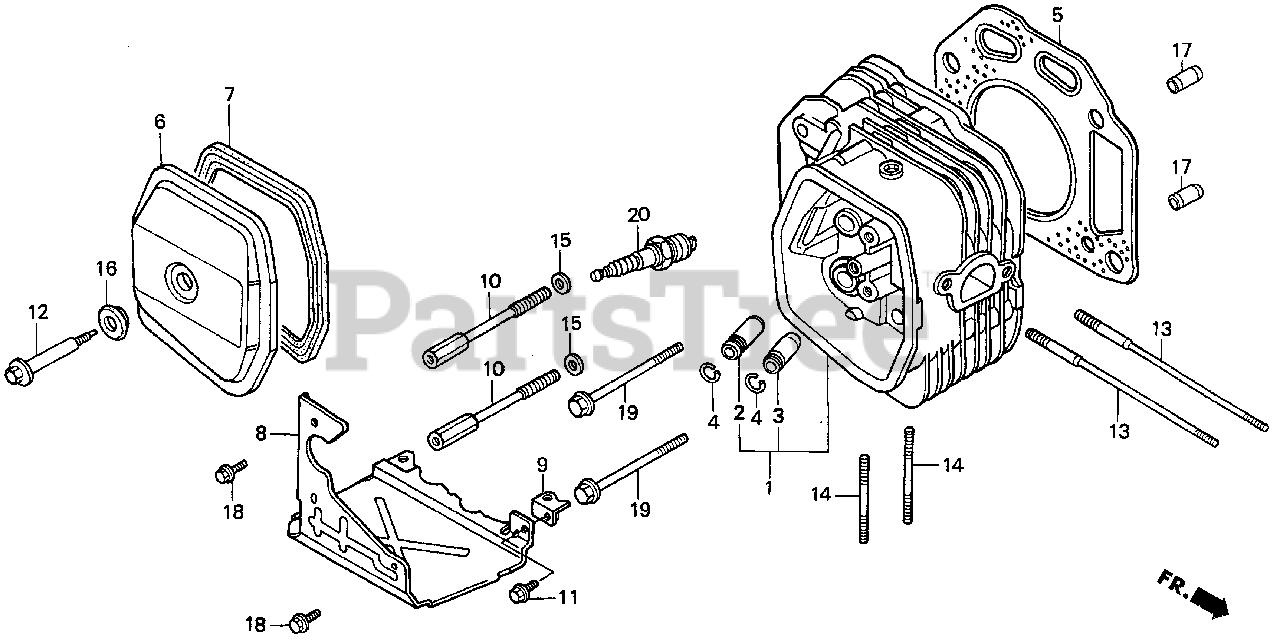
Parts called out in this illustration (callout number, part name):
1	CYLINDER HEAD
2	GUIDE, VALVE (OS)
3	GUIDE, EX. VALVE (OS)
4	CLIP, VALVE GUIDE
5	GASKET, CYLINDER HEAD
6	COVER, HEAD
7	GASKET, CYLINDER HEAD COVER
8	COVER (LOWER)
9	STAY, COVER (LOWER)
10	BOLT, SPECIAL HEAD COVER
11	BOLT, FLANGE (6X12) (CT200)
12	BOLT, HEAD COVER
13	BOLT, STUD (8X131.5)
14	BOLT, STUD
14	BOLT 2, STUD (8X32)
15	WASHER, SPECIAL (11X21X2.3)
16	WASHER, HEAD COVER
17	PIN A, DOWEL (12X20)
18	BOLT, FLANGE (6X12)
19	BOLT, FLANGE (10X80)
20	SPARK PLUG (BPR5ES) (NGK)
20	SPARK PLUG (W16EPR-U) (DENSO)
